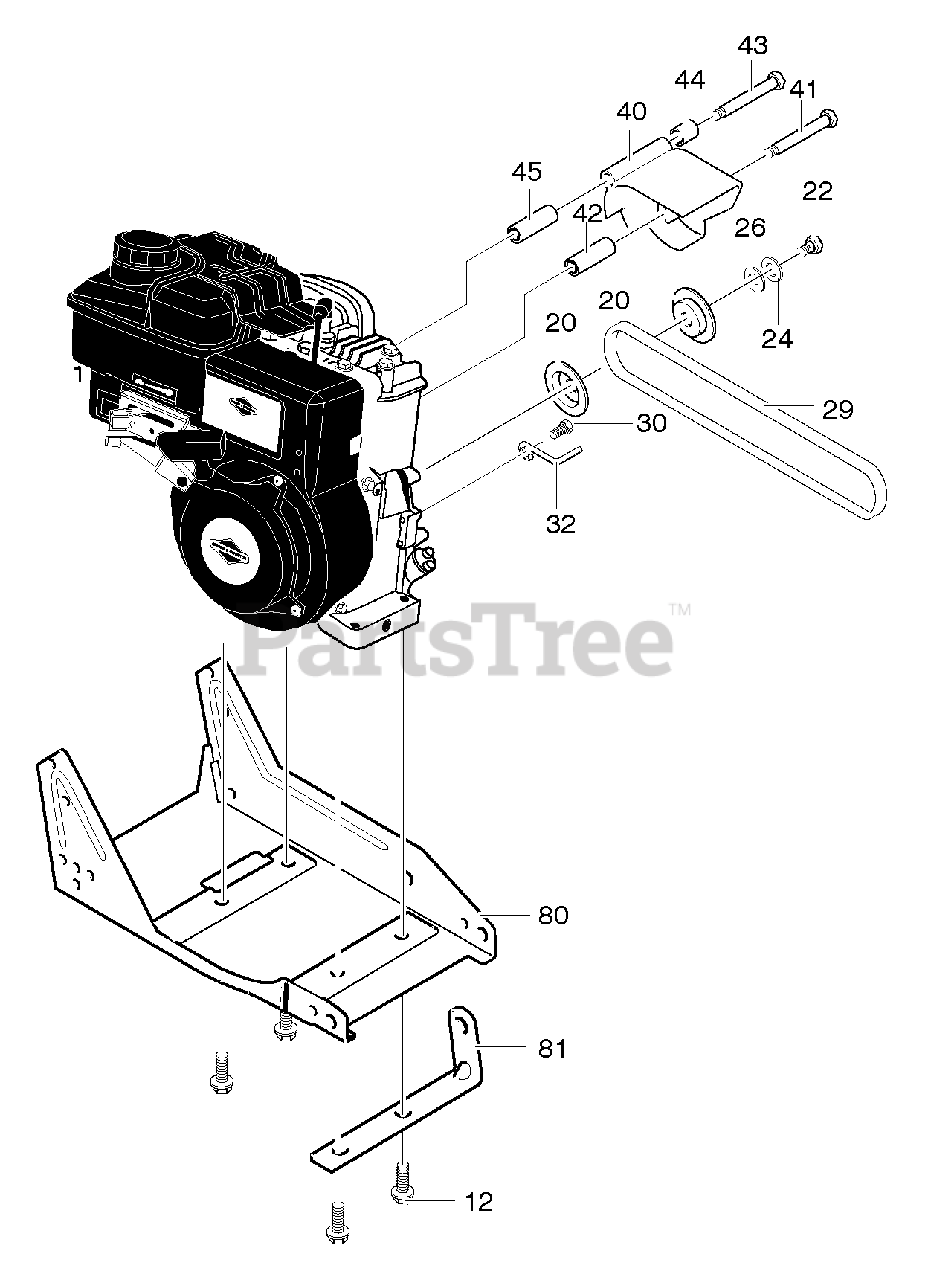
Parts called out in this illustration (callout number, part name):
10	Engine
12	Screw, 3/8-16x1.00
20	Pulley, Half
22	Screw, 5/16-24x1.00
26	Flatwasher
29	Belt, V4L 32.60LG
30	Screw and Washer Assy
32	Guide, Belt
40	Cover, Engine Pulley
41	Screw, 5/16-24x3.00
42	Spacer, Sleeve
43	Screw, 5/16-24x3.75
45	Spacer, Sleeve
80	Frame, Assy. Edger
